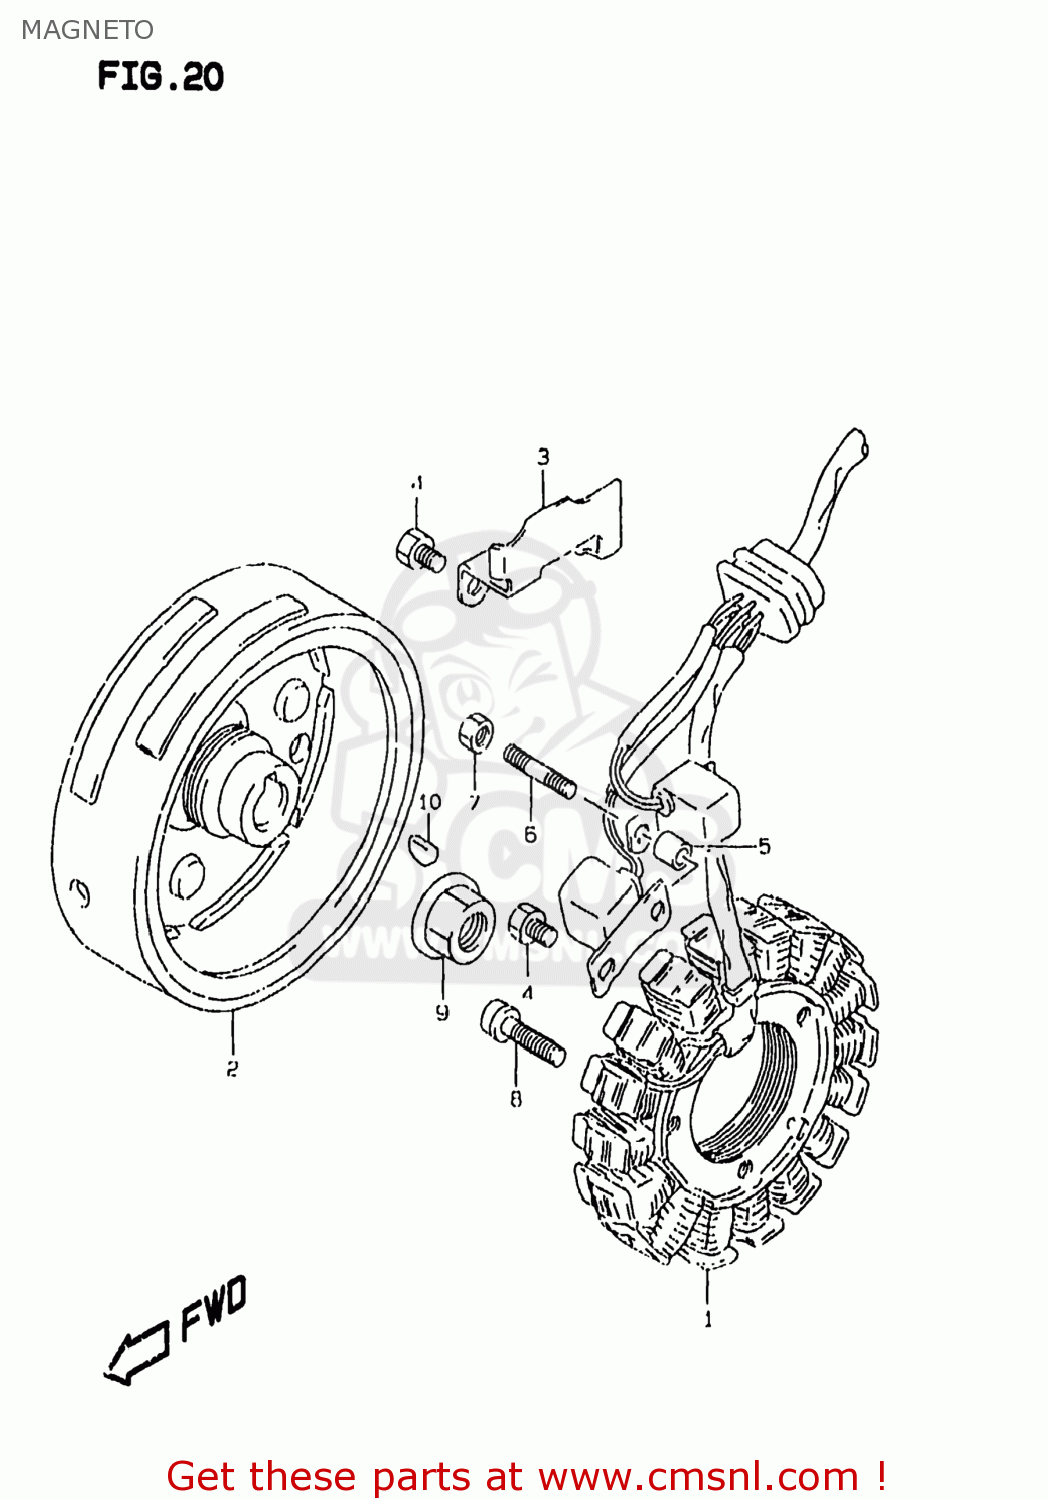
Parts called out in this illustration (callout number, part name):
1	STARTER ASSY
2	ROTOR ASSY
3	CLAMP,MAGNETO LEAD WIRE
4	BOLT(5X10)
5	SPACER(5.5X9.5X6.5)
6	BOLT,STUD(5X18)
7	NUT
8	BOLT,CL.COVER
9	NUT
10	KEY
